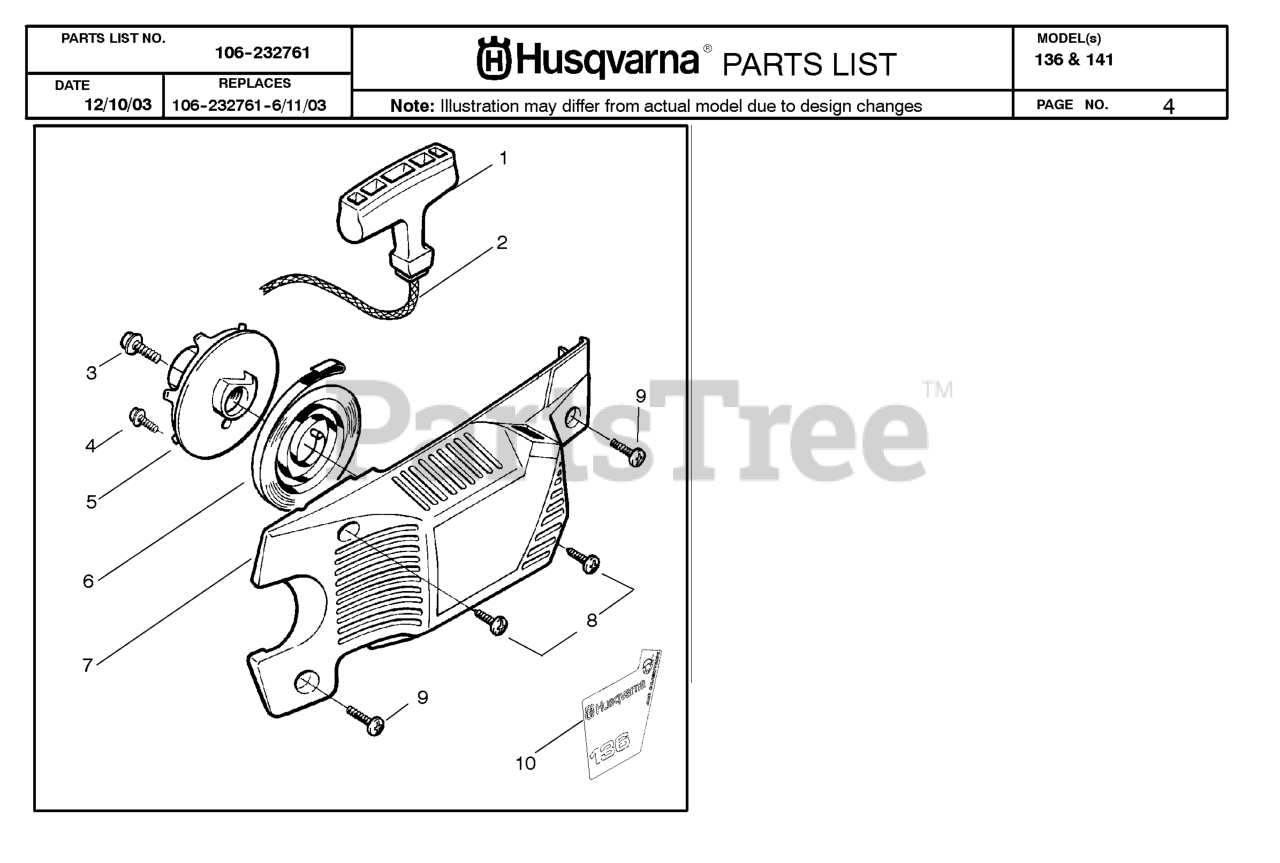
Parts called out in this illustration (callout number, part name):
1	STARTER HANDLE
5	PULLEY 36/41
6	RETURN SPRING
7	FAN HOUSING ASSEMBLY
8	SCREW,STRTR CVR 36/41
